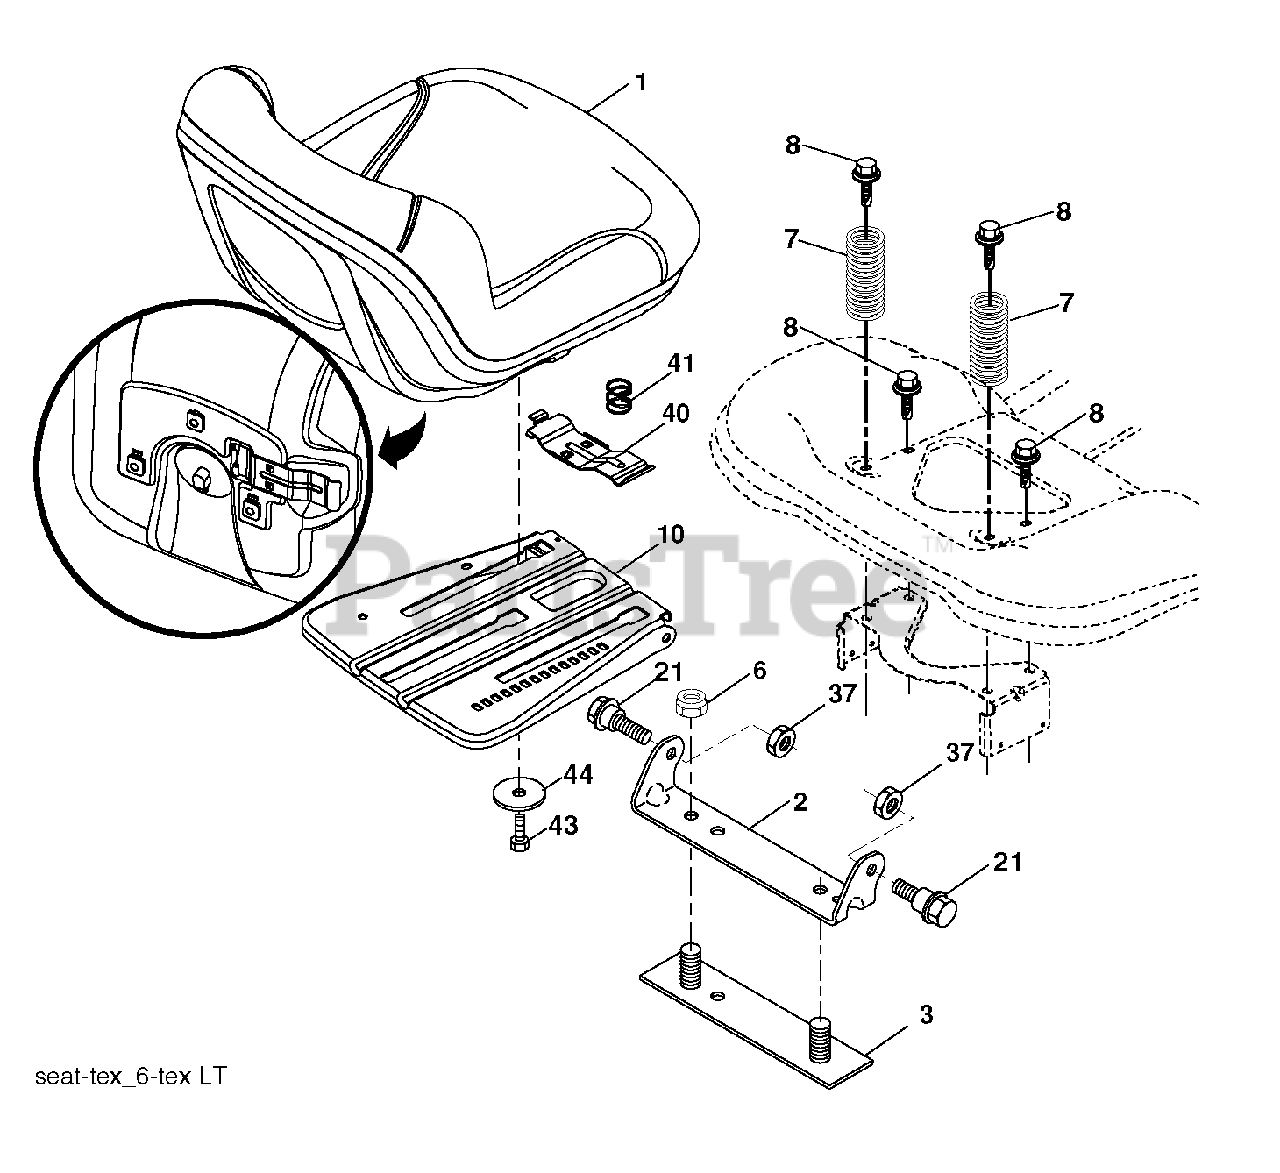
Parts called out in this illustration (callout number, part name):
1	SEAT.TH130.GREY.HUSQ.TEX
2	BRKT.PIVOT.FENDER
3	STRAP
6	NUT
7	SPRING COMPRESSION
8	BOLT, 5/16-18 X 1 3/4
10	PAN.ASM.SEAT.3PT
21	BOLT.SHOULDER.5/16-18
37	NUT.71038.31-18.HEX.NYLOCK
40	HANDLE.SLIDE.SEAT.TEX.BLACK
41	SPRING.LATCH.SEAT.TEX
44	WASHER 13/32 X 2-3/8 X 12GA
